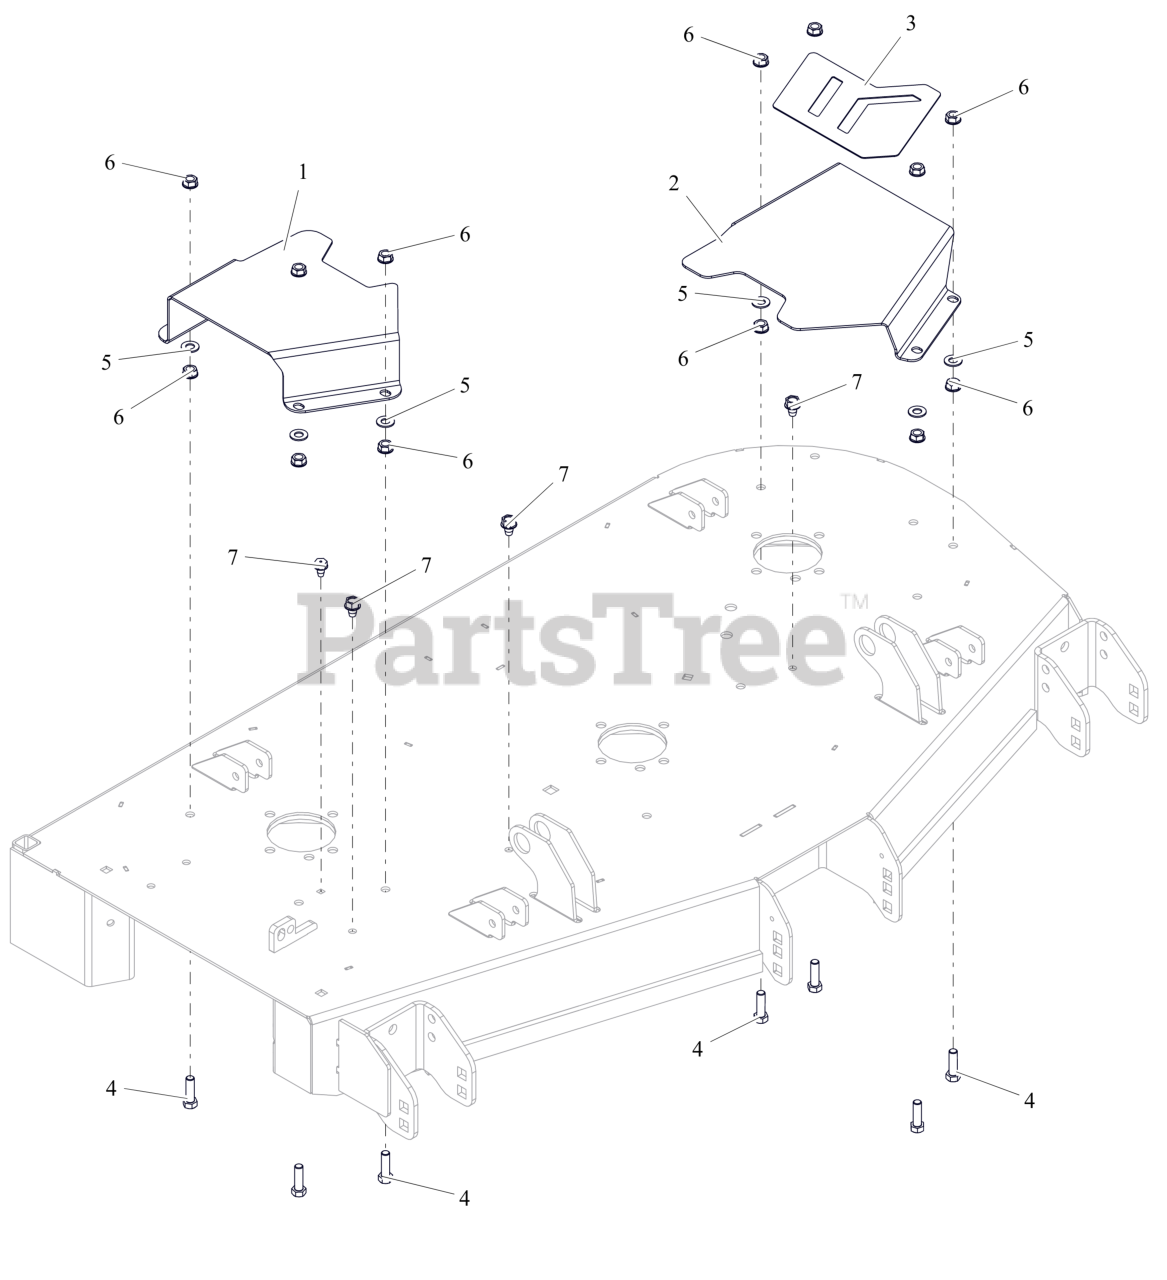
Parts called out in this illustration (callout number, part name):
1	COVER, BELT 48" RIGHT
2	COVER, BELT 48" LEFT
3	GRIP TAPE 48 BELT COVER
4	BLT, HEX .38-16X1.25 G5 ZCC
5	WSHR,FLT .406X.812X.065 ZCC
6	NUT, SPNLK-FLG .38-16 G5 ZCC
7	SCR-TAP .
